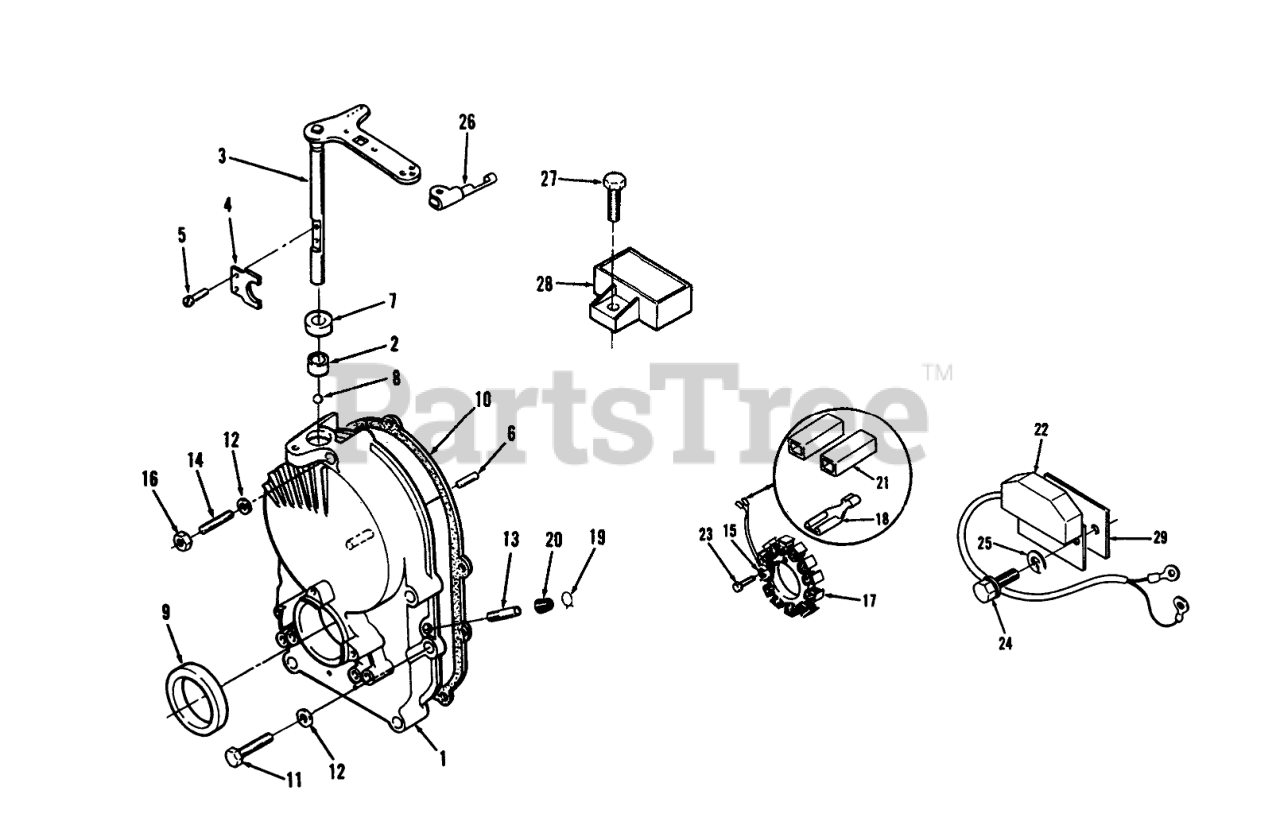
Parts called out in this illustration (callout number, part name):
10	Gasket
11	Bolt
12	WASHER
14	Stud
15	Washer-Lock
16	Nut
17	Stator (Includes Terminals)
18	Stator Leads Terminal
21	Body-Terminal Connector Kit(Includes Terminals)
22	Control-Ignition
23	Screw-HH
24	Bolt
25	WASHER-LOCK
27	SCREW-HWH
28	Regulator
29	Insulator
